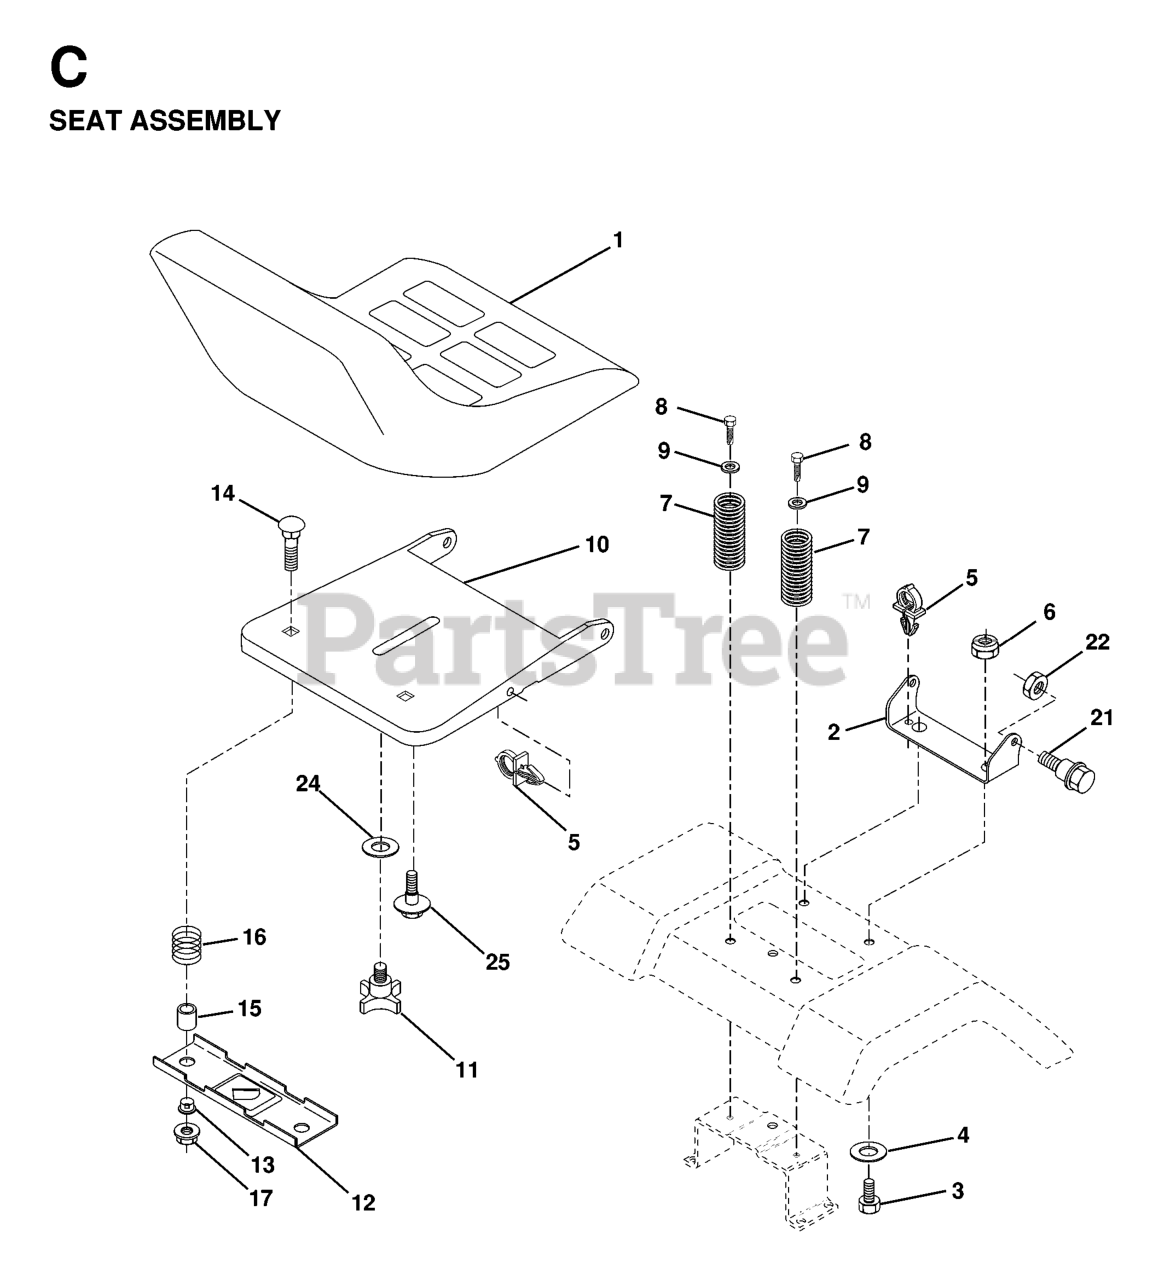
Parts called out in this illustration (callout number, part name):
1	SEAT, GRAY
2	SEAT PIVOT BRKT
3	BOLT
6	NUT
7	SPRING COMPRESSION
8	SCREW GTV
9	WASHER
10	PAN, SEAT
11	KNOB 1/2" YT
12	BRKT SWITCH
14	BOLT.ROUND.HEAD.SQUARE.NECK
15	SPACER SPLIT 28X.96
17	NUT T
21	BOLT SHOULDER 5/16-18
22	NUT.71038.31-18.HEX.NYLOCK
25	BOLT,SHOULD
